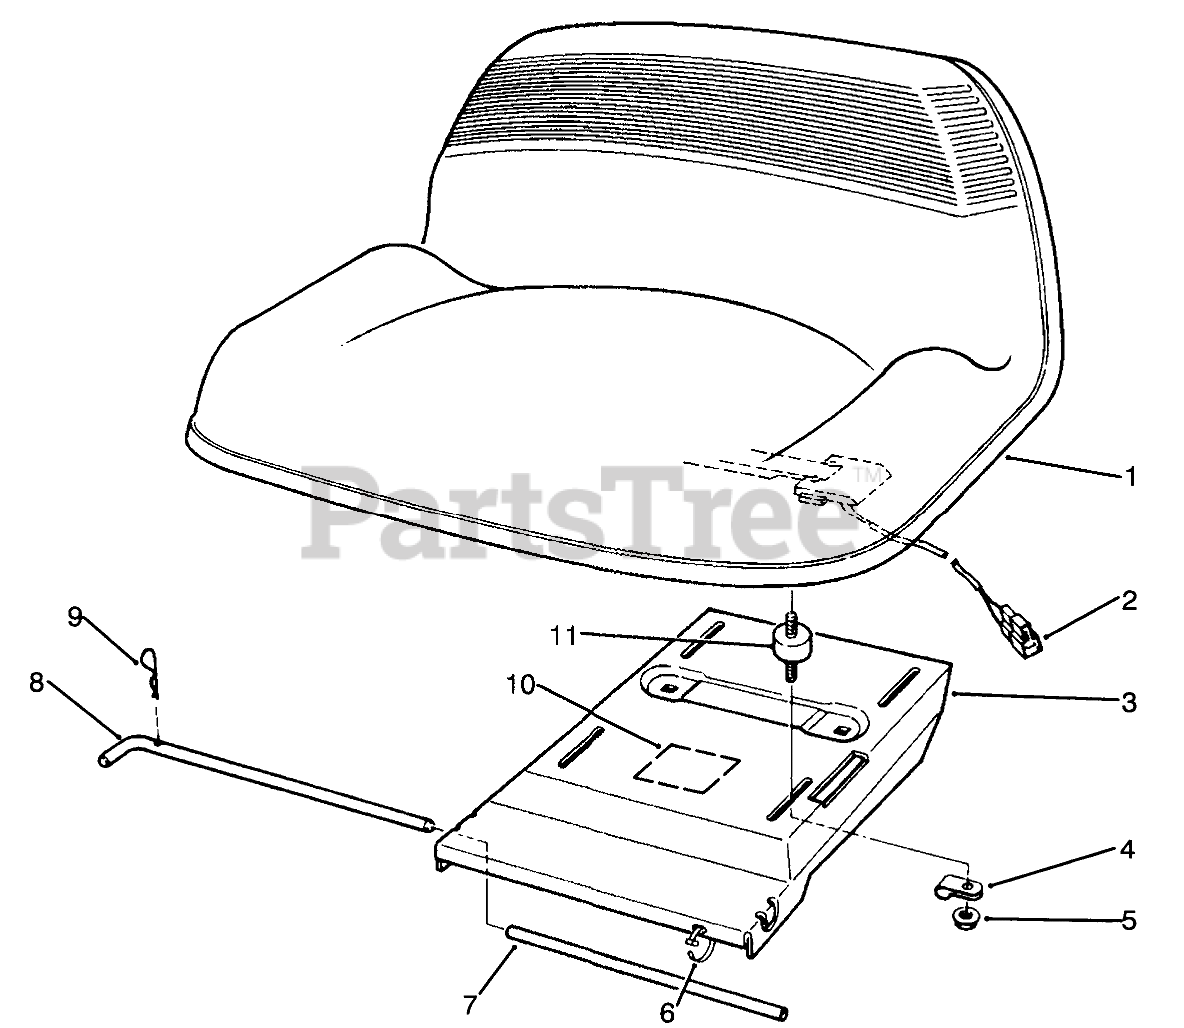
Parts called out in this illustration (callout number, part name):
1	SEAT
2	SWITCH-SEAT
3	Base-Seat
4	CLAMP
5	NUT-HF
6	TIE-CABLE
7	TUBE-SEAT
8	ROD-SEAT BASE
9	PIN-COTTER
10	DECAL-EUROPE
11	ISOLATER-SEAT
